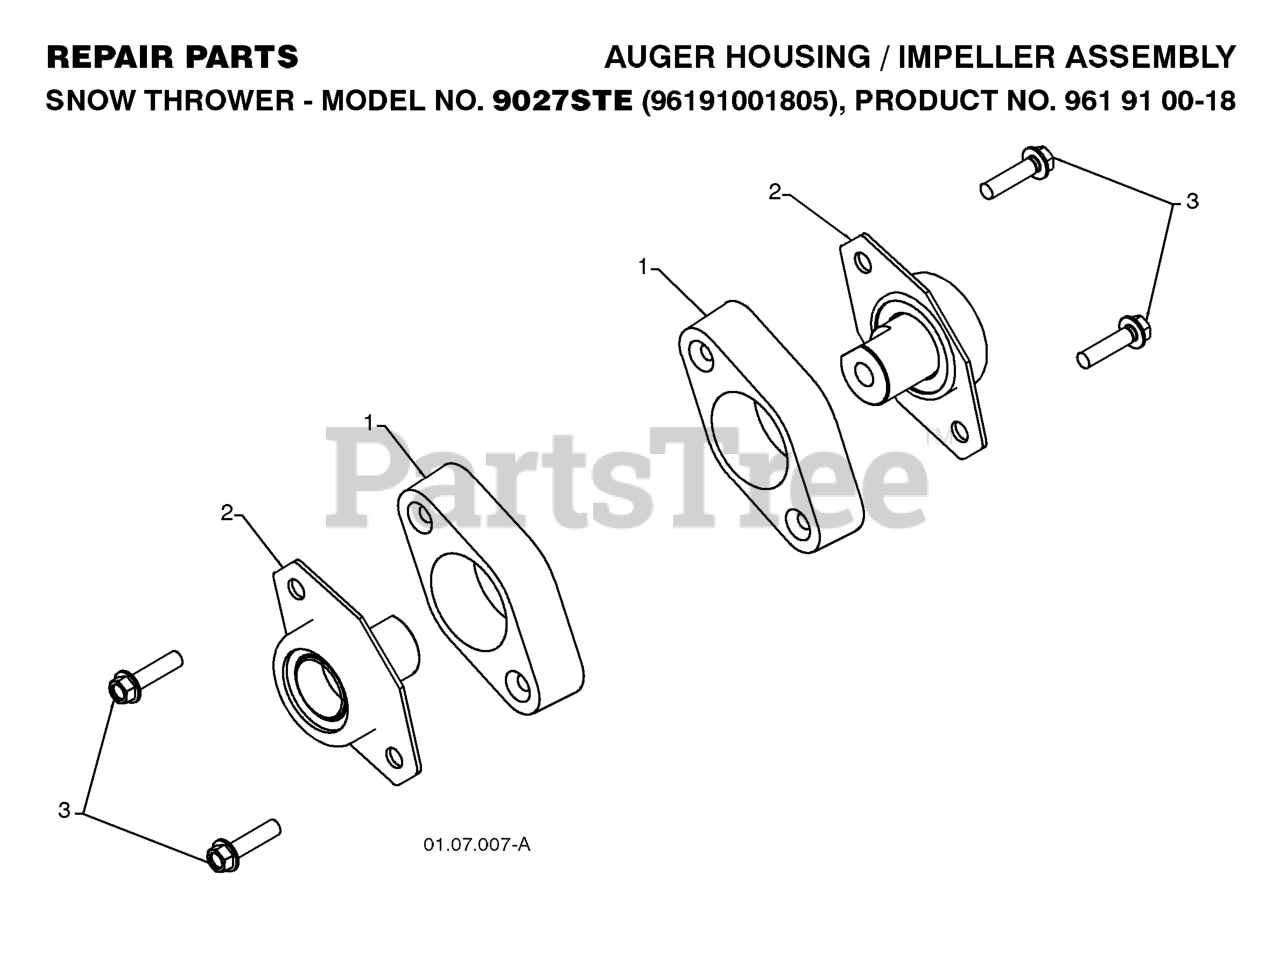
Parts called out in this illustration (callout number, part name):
1	BEARING RETAINER, PLASTIC
2	BEARING.BALL.AUGER
3	SCREW, HEX HD 5/16X1
